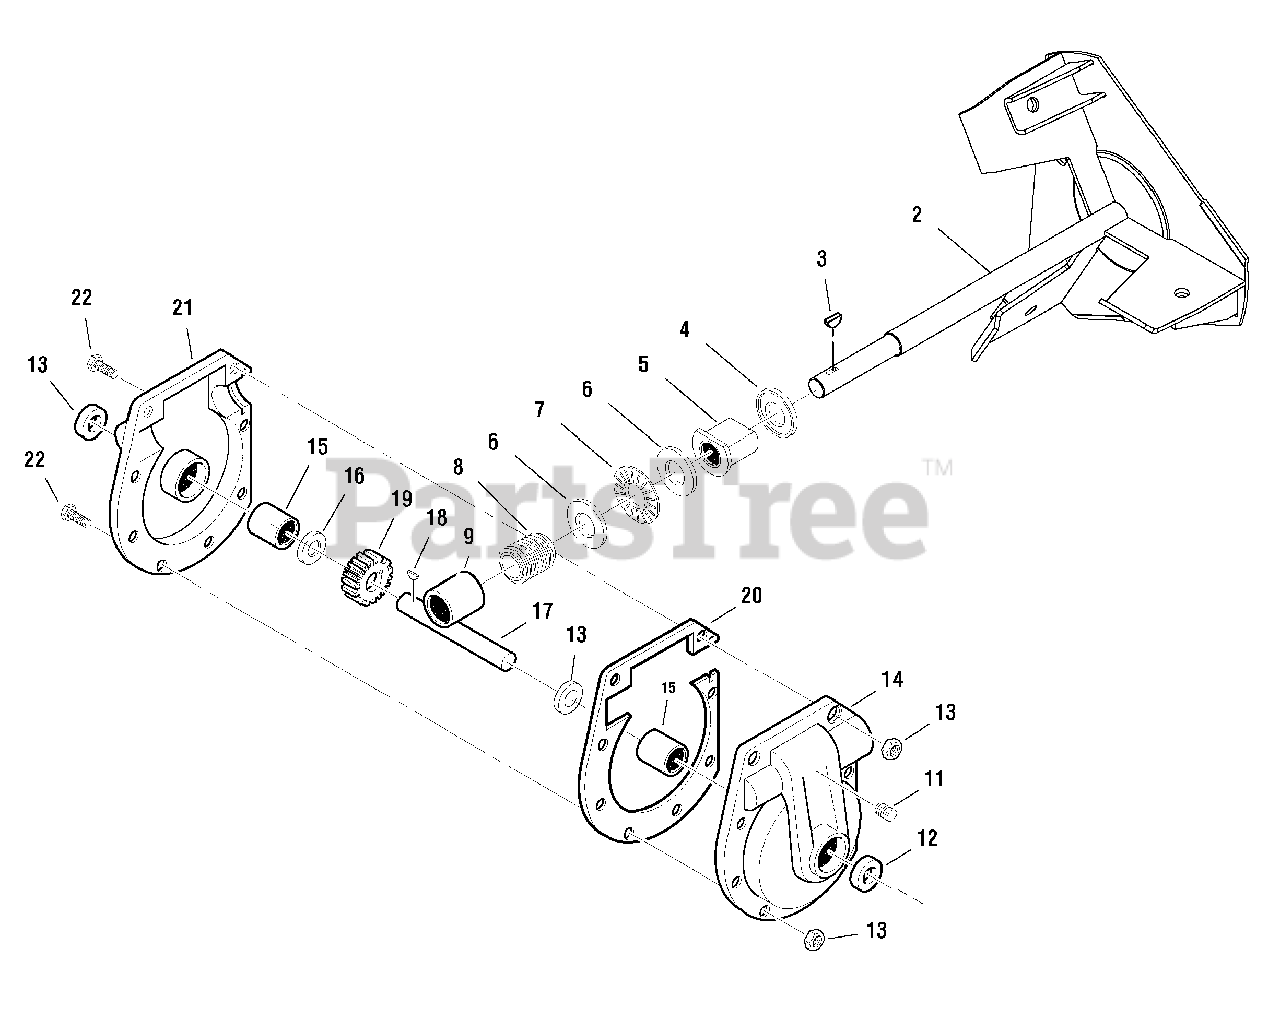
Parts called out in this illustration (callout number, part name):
2	IMPELLER ASSEMBLY
3	KEY
4	RING
5	BEARING, Flange, 3/4 x 1-1/8
6	WASHER, 3/4 x 1-1/4
7	BEARING, Roller, 3/4 x 1-1/4
8	ROLLED WORM CASE
9	SLEEVE, Brearing, 3/4 x 7/8
11	PLUG, Pipe, 1/4-18
12	SEAL, Oil
13	NUT, Hex-Flange, Locking, 5/16-24
14	GEAR CASE, L.H.
15	SLEEVE, Bearing
16	THRUST WASHER, 1 x 1.54
17	SHAFT, Auger Output
18	KEY, Woodruff, 1-3/4 x 1/4
19	GEAR, Worm
20	GASKET, Gearbox
21	GEAR CASE, R.H.
22	CAPSCREW, Hex, 5/16 - 24 x 1
